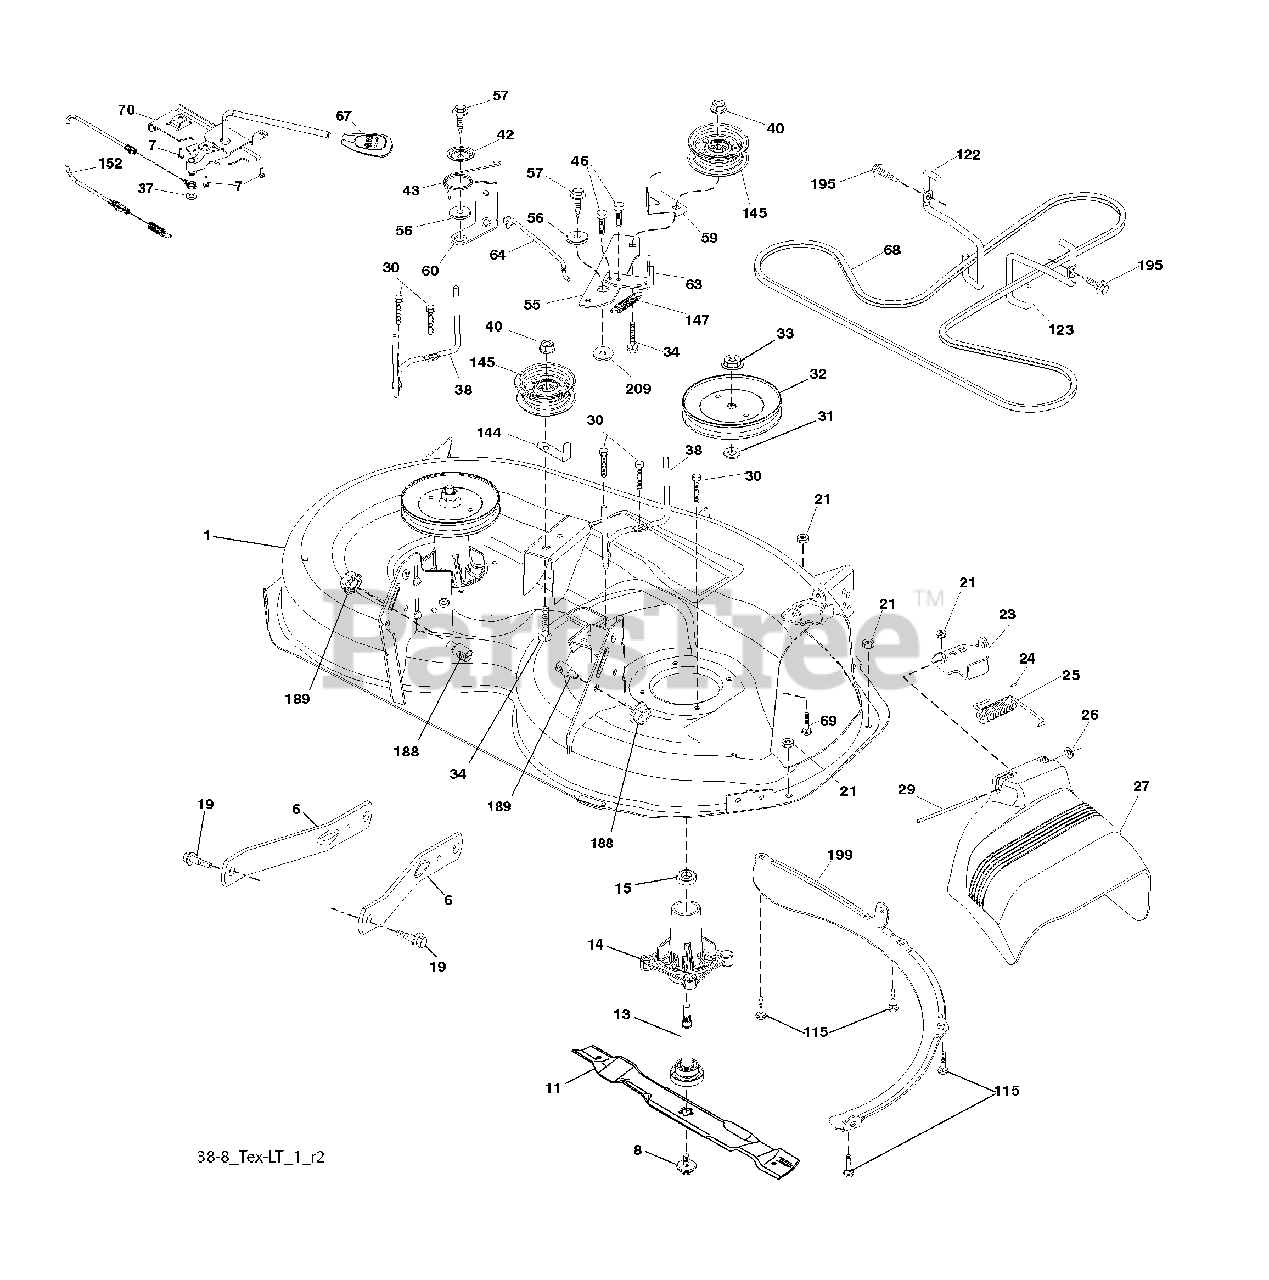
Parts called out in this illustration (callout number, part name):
1	Mower Housing
6	Arm Suspension
7	Screw #10 x 0.750 BOS Thread
8	Bolt/Washer asm 7/16-20 unf
11	Blade
13	Shaft Assembly, Mandrel
14	Housing, Mandrel
15	Bearing, Ball, Mandrel
19	Bolt, Shoulder
21	Nut, Crownlock 5/16-18 unc
23	Bracket, Deflector
24	Cap, Sleeve
25	Spring, Torsion, Deflector
27	Shield, Deflector
29	Rod, Hinge
30	Screw Thdrol Rolling Wsh Hd
31	Washer, Spacer
32	Pulley, Mandrel
33	Nut, Toplock, Flanged
34	Bolt Carr Sh. 3/8-16 x 1-1/2 Gr. 5
37	Washer
38	Keeper Belt LH Mandrel
40	Nut, Lock Flg. 3/8-16 unc
42	Spring Torsion Brake
43	Spring Torsion Retainer
46	Screw 1/4-20 x 5/8
55	Arm, Idler
56	Spacer, Retainer
57	Screw 3/8-16 x 1
59	Guard, Tuv Idler
60	Arm Brake Mower RH
63	Arm Brake Mower LH
64	Link Brake
67	Handle Clutch Cable
69	Bolt
70	Clutch Asm Manual
115	Bolt Carr. 5/16-18 x 5/8
116	Bolt, Shoulder
117	Wheel, Gauge
118	Nut Lock 3/8-16 unc
119	Washer 3/8 x 7/8 x 14 Ga.
122	Keeper Belt Engine LH
123	Keeper Belt Engine RH
144	Keeper Belt
145	Pulley Idler
147	Spring Return
149	Retainer Spring
152	Manual Clutch Cable
188	Stud Fastener
189	Nut Lock Hex Flange
195	Screw 3/8-16 x 3/4
199	Baffle Vortex
209	Washer 13/32 x 2 x 10
209	Mandrel Assembly
209	Replacement Mower, Complete
